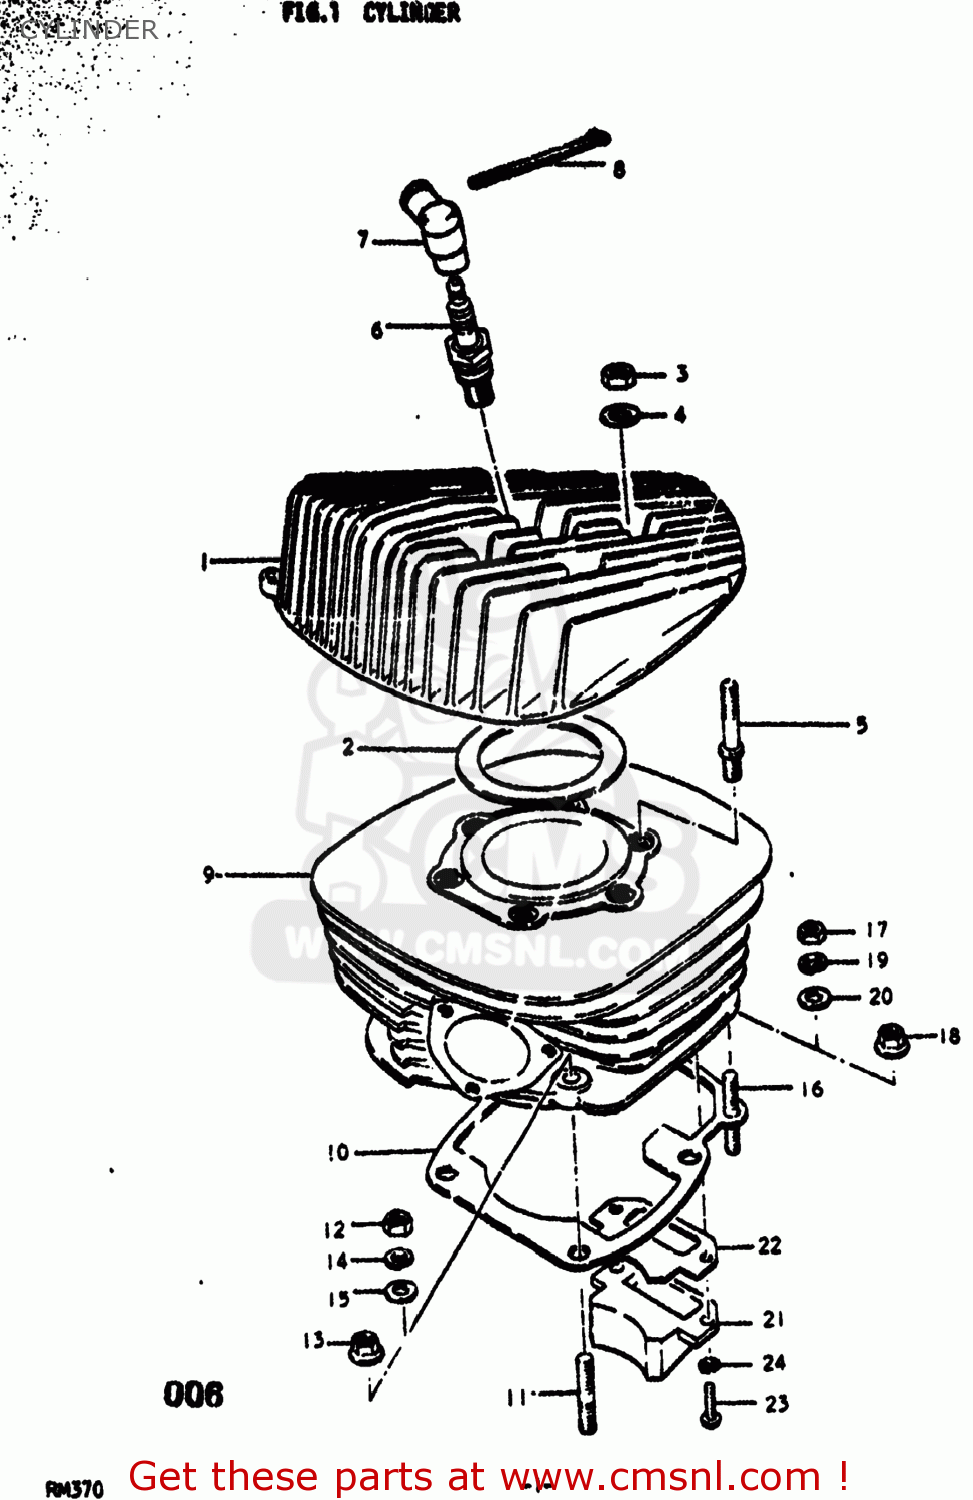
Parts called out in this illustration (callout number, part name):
1	HEAD,CYLINDER
2	GASKET,CYLINDER HEAD (NAS)
3	NUT (8MM)
4	WASHER
5	BOLT,STUD
6	SPARK PLUG
7	CAP,SPARK PLUG
8	CLAMP
9	CYLINDER
10	GASKET,CYLINDER (MCA)
11	STUD 10X30
12	NUT
13	NUT
14	LOCK WASHER
15	WASHER
16	STUD BOLT
17	NUT
18	NUT
19	LOCK WASHER
20	WASHER
21	VALVE ASSEMBLY,REED
22	GASKET,REED VALVE (MCA)
23	SCREW
24	LOCK WASHER
